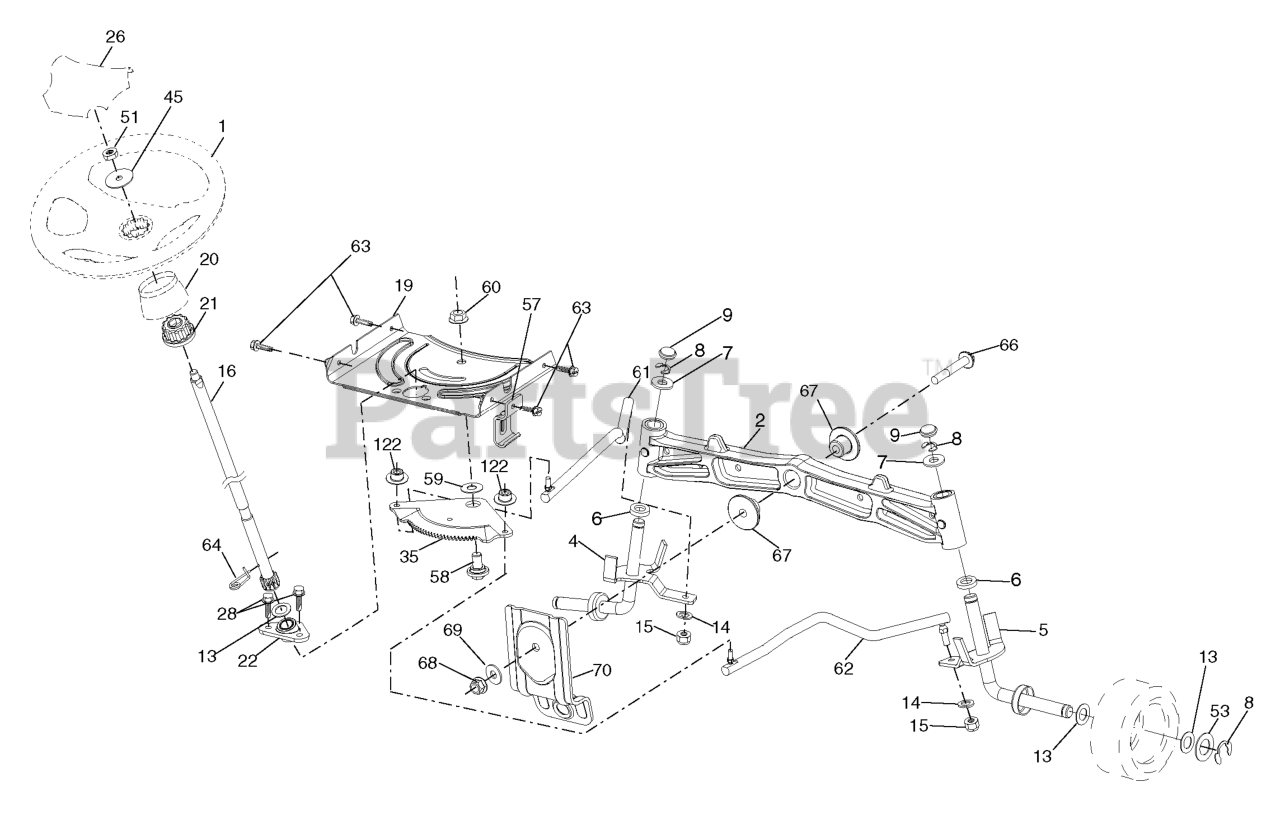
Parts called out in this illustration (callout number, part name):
1	Wheel, Steering
2	Axle Asm., Front
4	Spindle Asm., LH
5	Spindle Asm., RH
6	Bearing, Race Thrust Harden
7	Washer 25/32 x 1-5/8 x 16 Ga.
8	Ring, Clip #T5304-75
9	Cap, Spindle
13	Washer 25/32 x 1-1/4 x 16 Ga.
14	Washer, Lock Hvy Hlcl Spr 3/8
15	Nut, Crown Lock 3/8-24 unf
16	Shaft Steering
19	Plate Steering
20	Boot, Steering
21	Adapter, Wheel Steering
22	Strg. Supt. Lower
26	Insert, Wheel Steering
28	Screw 3/8-16 x 3/4
35	Gear, Sector Plate
45	Washer 11/32 x 2-3/8 x 12 Ga.
51	Nut Hex Jam Toplock 1/2-20 unf
53	Washer Hardened .793 x 1.637 x .060
57	Bracket Upstop
58	Bolt Shoulder Sector Pivot CFM
59	Washer Thrust Sector Steering
60	Nut Flange Lock 5/8-11
61	Draglink, LH
62	Draglink, RH
63	Screw 5/16-18 x 3/4
64	Retainer Clip Spring Steering
66	Bolt Hex Fghd 7/16-14 x 3 Serr
67	Bushing PM Front Axle
68	Nut Lock Flange 7/16-14 Gr. 5
69	Washer 1.5 x .505 x .118
70	Bracket Deck Susp. Front
122	Cap Gear Sector Tex
